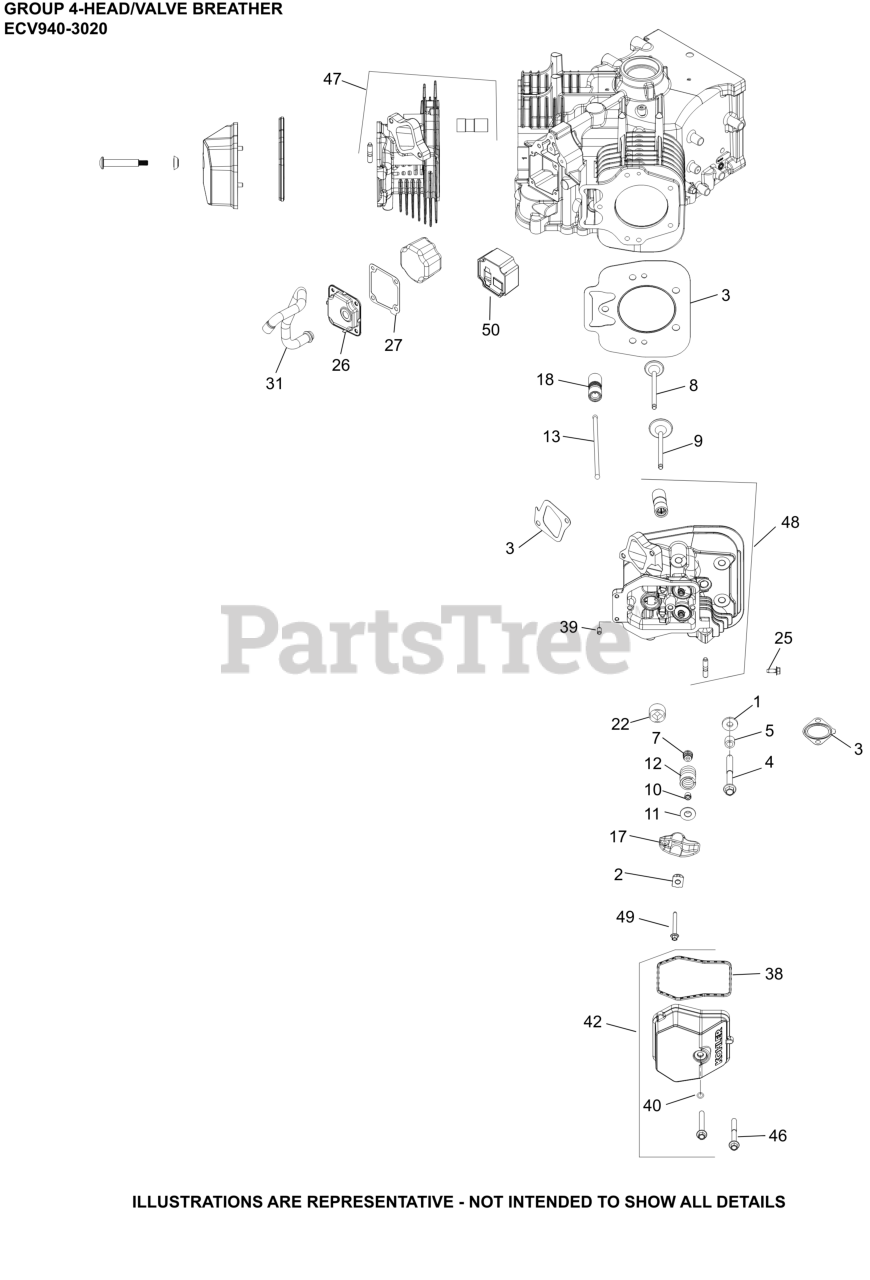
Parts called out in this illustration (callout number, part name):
1	WASHER, FLAT 13/32"
2	PIVOT, ROCKER ARM
3	KIT, CYLINDER HEAD GASKET
4	SCREW, FLG M10X1.5X90
7	SEAL, VALVE BAND
8	VALVE, EXHAUST
9	VALVE, INTAKE
10	KIT, RETAINER
11	CAP, VALVE SPRING
12	SPRING, VALVE
13	ROD, PUSH
17	ARM, ROCKER
18	LIFTER, HYDRAULIC VALVE (SERVICE)
22	PLUG, PIPE 3/4 NPTF SQUARE
25	SCREW, THREAD FORMING
26	KIT, BREATHER ASSEMBLY
27	GASKET, BREATHER
31	HOSE, BREATHER
38	SEAL, ALUMINUM VALVE COVER (BLUE)
39	PIN, ROLL
40	O-RING, VALVE COVER SCREW
42	KIT,VALVE CVR (NO FILL)-USE 62 096 50-S
42	KIT, VALVE COVER ASSEMBLY
46	SCREW, HEX FLANGE
47	KIT, #1 CYLINDER HEAD COMPLETE
48	KIT, #2 CYLINDER HEAD COMPLETE
49	SCREW, HEX FLANGE
50	FILTER, BREATHER
